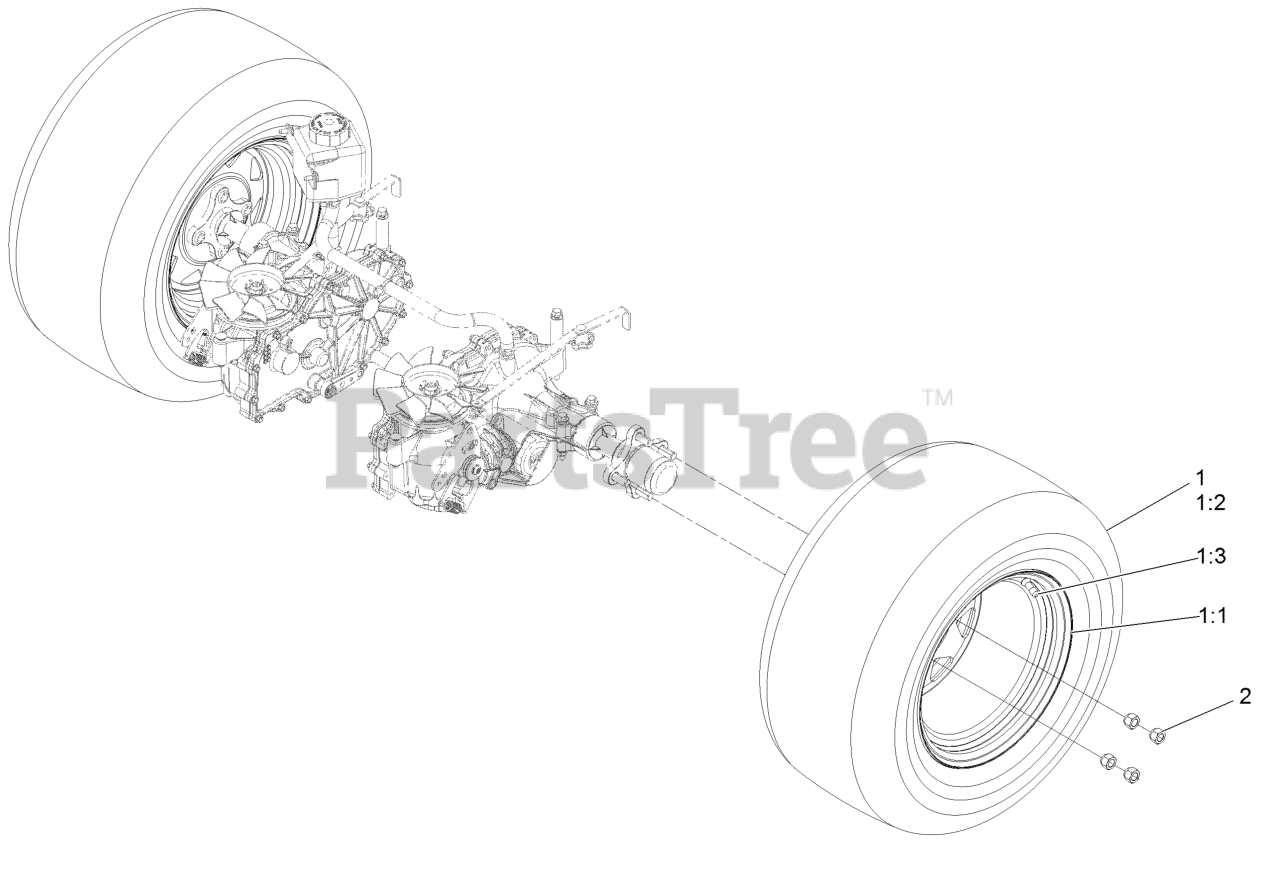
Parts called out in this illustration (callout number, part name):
1	Wheel And Tire ASM
1:1	Wheel Rim 12X8.5
1:2	Tire
1:3	Stem-Valve
2	Nut-Lug 1/2-20
